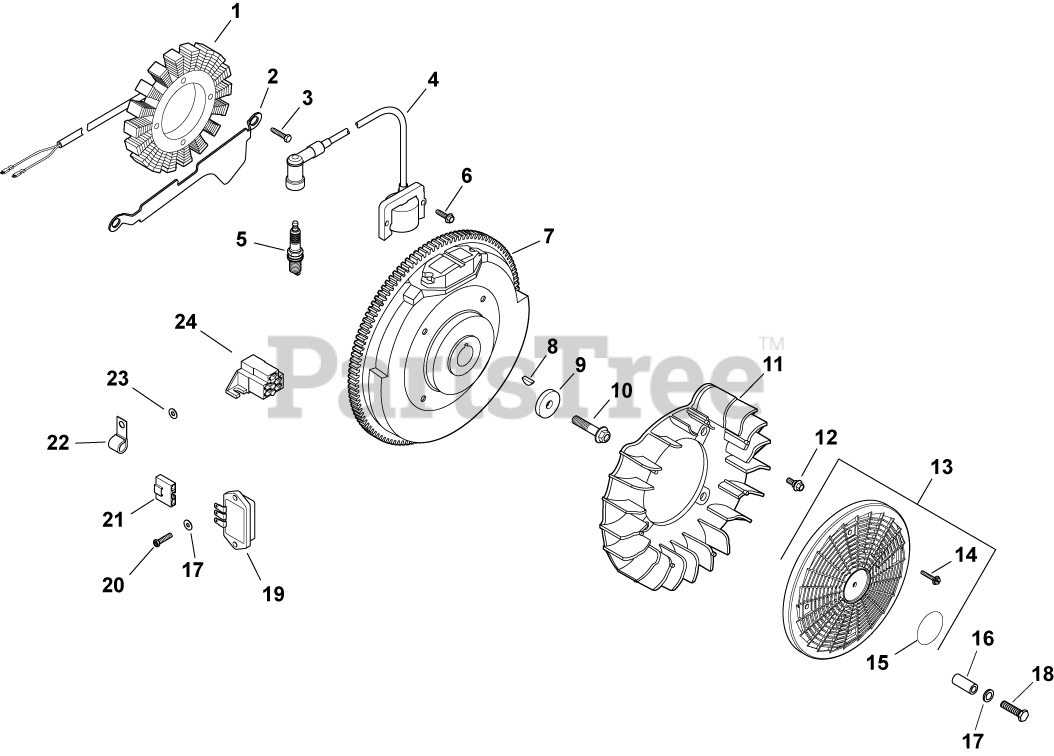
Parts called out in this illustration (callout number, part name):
1	KIT, 15 / 20 AMP STATOR
2	BRACKET, STATOR WIRE-USE 24 126 139-S
3	SCREW, M5X0.8X25 - (#25086402S)
4	MODULE, IGNITION-USE 24 584 45-S
5	PLUG, SPARK (STD)
6	SCREW, FLG THD FRM M5X.8X20-(#25086399S)
8	KEY, 3/16" X 5/8"
9	WASHER, FLAT 13/32"
10	SCREW, FLG M10X1.5X45 - (#25086361S)
11	FAN (WITH HOLE)-USE 24 157 16-S
12	BOLT, SHOULDER
13	KIT, GRASS SCREEN
14	SCREW, WSH HD TAP #8-18X1/2"
15	DECAL, GRASS SCREEN USE 24 113 499-S
16	SPACER - DISCONTINUED
17	WASHER, FLAT 3/16"
18	SCREW, SLT HD CAP M4X0.7X25
19	REG/RECT-15 AMP (KM)-USE 41 403 10-S
20	SCREW, PHL HD #11-16X7/8"
21	CONNECTOR, BODY (KM)-USE 25 155 41-S
22	CLIP, CABLE
23	WASHER, FLAT 1/4" (O.D. 1/2")
24	CONNECTOR
